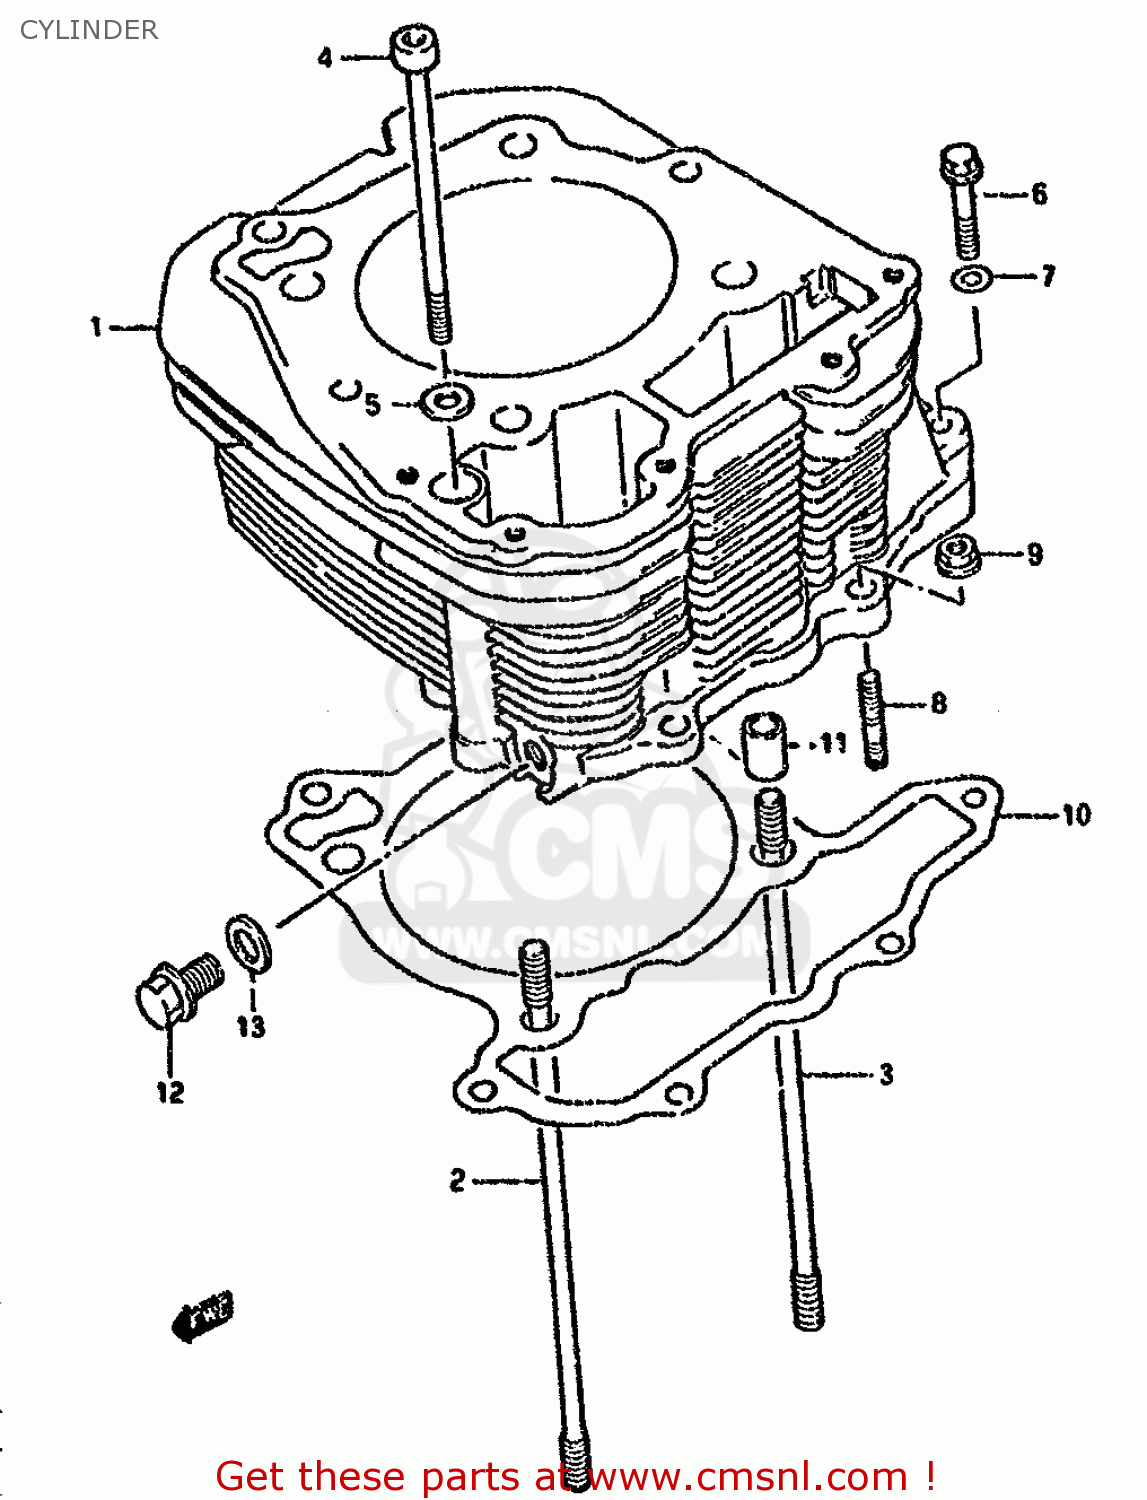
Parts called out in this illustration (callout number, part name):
1	CYLINDER
2	BOLT,STUD
3	BOLT,STUD(10X195)
4	BOLT L:115
5	GASKET(7.2X13X1.2) (NAS)
6	BOLT
7	GASKET(5.8X13X1.2) (NAS)
8	BOLT,STUD
9	NUT
10	GASKET,CYLINDER (NAS)
11	PIN
12	BOLT
13	GASKET(10.2X20X2).3 (NAS)
